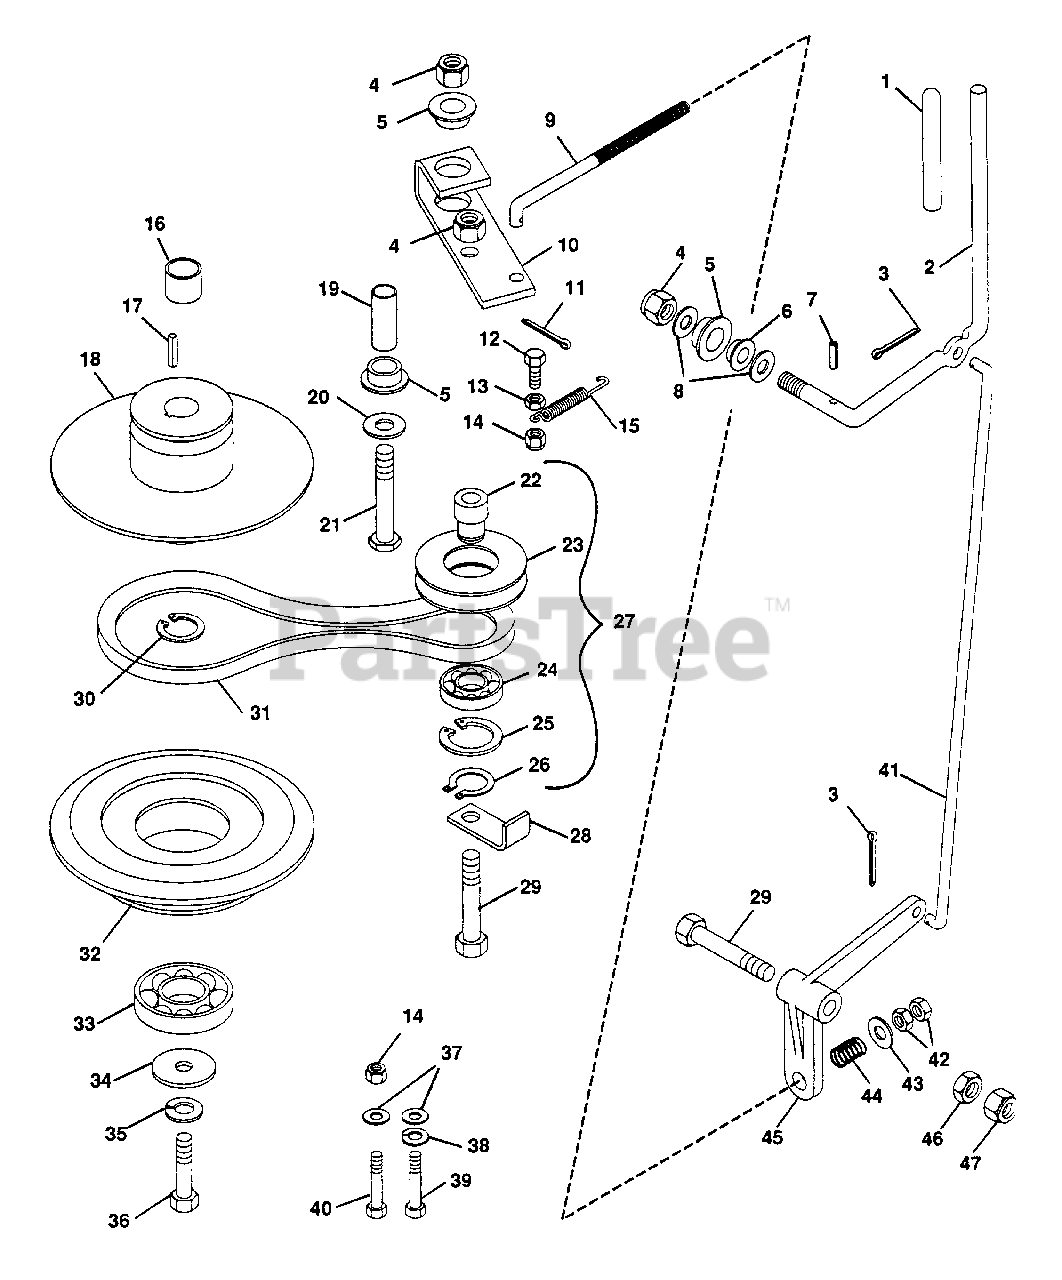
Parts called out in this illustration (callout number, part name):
1	GRIP, PTO LEVER
2	LEVER, PTO ACTUATING
3	PIN, COTTER .09X.75
4	NUT, LOCK 1/2-13
5	BUSHING, FLANGE NYLON
6	BUSHING, FLANGE NYLON
7	PIN, SPRING .187X1.000
8	WASHER, FLAT .531X1.250X.100
9	ROD, PTO CLUTCH ACTUATING
10	ARM, IDLER PIVOT
11	PIN, COTTER .125X.75
12	BOLT, HEX 5/16-18X1.00
13	NUT, HEX 5/16-18
14	NUT, LOCK 5/16-18
15	SPRING, PTO RETURN
16	SPACER, MANUAL START
17	KEY, SQUARE .250X1.250
18	HUB, PTO AND DRIVE CLUTCH
19	BUSHING, ST. .560X.745X2.04 STL.
20	WASHER, FLAT .531X1.062X.095
21	BOLT, HEX 1/2-13X2.75 SPECIAL
22	BUSHING, FLANGE STEEL
23	SHEAVE, IDLER
24	BEARING, BALL
25	RING, RETAINING
26	RING, RETAINING
27	ASSEMBLY, IDLER SHEAVE
28	GUIDE, BELT
29	BOLT, HEX 1/2-13X2.50
30	RING, RETAINING
31	V-BELT, PTO CLUTCH
32	SHEAVE, MOWER CLUTCH
33	BEARING, BALL 1.574X3.149X.708
34	WASHER, SPECIAL
35	WASHER, LOCK 7/16 REG.
36	BOLT, HEX 7/16-20X2.50
37	WASHER, FLAT .344X.688X.065
40	BOLT HEX 5/16-18X1.75
41	ROD, PTO CONTROL
42	NUT, HEX 3/8-16
43	WASHER, FLAT .406X.812X.065
44	SPRING, COMP. 1X.78X338
45	LEVER, PTO CLUTCH
46	NUT, JAM 1/2-13 HEX
47	NUT, LOCK 1/2-13
